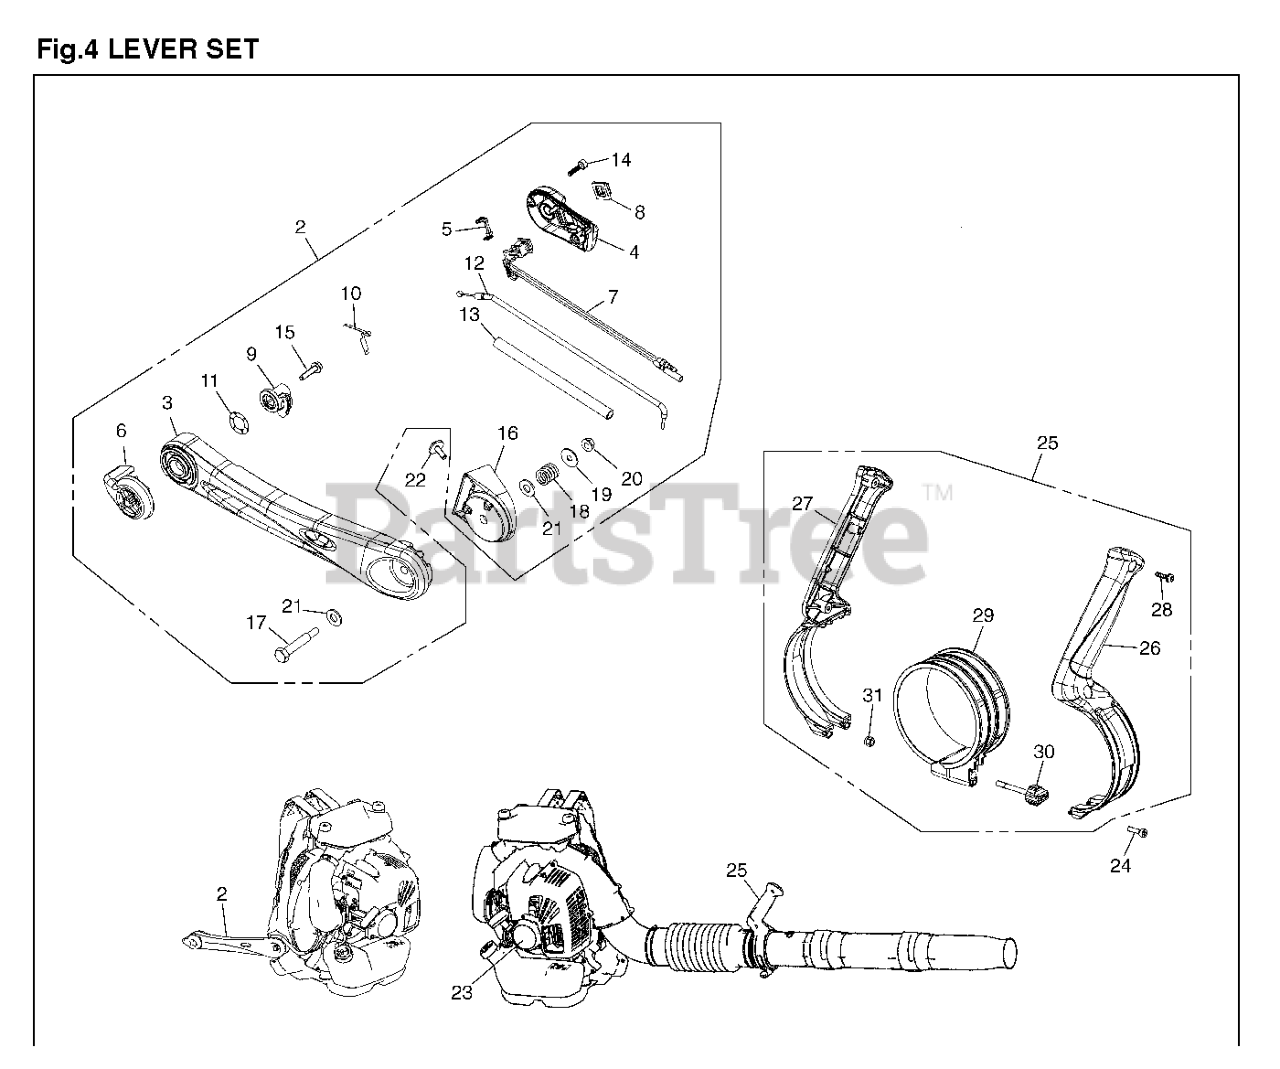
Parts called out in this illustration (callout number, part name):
2	LEVER,SET
6	LEVER,THROTTLE
8	CAP SWITCH
10	PLATE, CONTACT
11	WASHER WAVE
15	BOLT
19	WASHER Z349525440
20	NUT 8488646000
23	RECOIL LABEL
25	GRIP ASSY
26	GRIP,RIGHT
27	GRIP,LEFT
